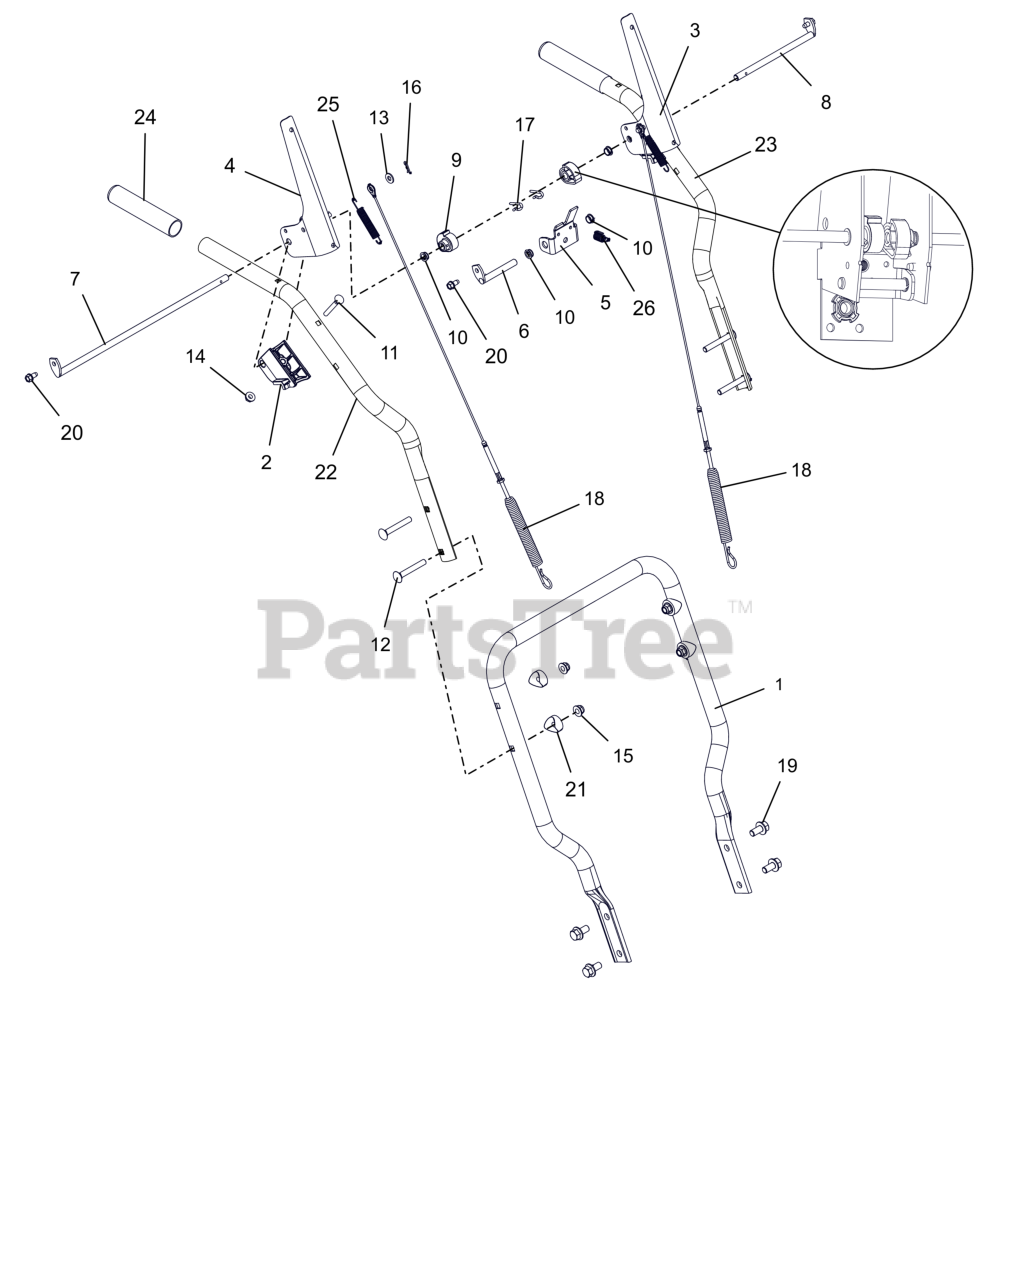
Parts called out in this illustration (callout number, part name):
1	HANDLEBAR, LOWER (COMPACT)
2	BLOCK, CLUTCH PADDLE
3	LEVER, CLUTCH-LH
4	LEVER, CLUTCH-RH
5	BRACKET, INTERLOCK ARM
6	ROD, PIVOT - INTERLOCK
7	ROD, PADDLE MOUNT - LONG
8	ROD, PADDLE MOUNT - SHORT
9	CAM, INTERLOCK
10	BUSHING, POLYLINER-.38 SNAPIN
11	BLT-RDHDXLSQNK .25-20X2.0 G5YZ
12	BLT, RHSN .31-18X2.25 G5 ZCC
13	WSHR,FLT .281X.625X.065 ZCC
14	NUT-LK-TOP-FLG .250-20 GF ZCC
15	NUT,LK-NYL-FLG .31-18 G5ZC120
16	PIN, HAIR #178 .06X.77 ZCC
17	PIN, SPRING CLIP
18	CABLE, AUGER & UPPER TRACTION
20	SCR-TAP .25-20X.50 HWH ZCC
21	SPACER, HANDLEBAR
22	HANDLEBAR, UPPER - RH
23	HANDLEBAR, UPPER - LH
24	GRIP,HANDLE-GRAY
25	SPRING, EXTENSION
26	SPRING-EXT .047X.438X1.45
